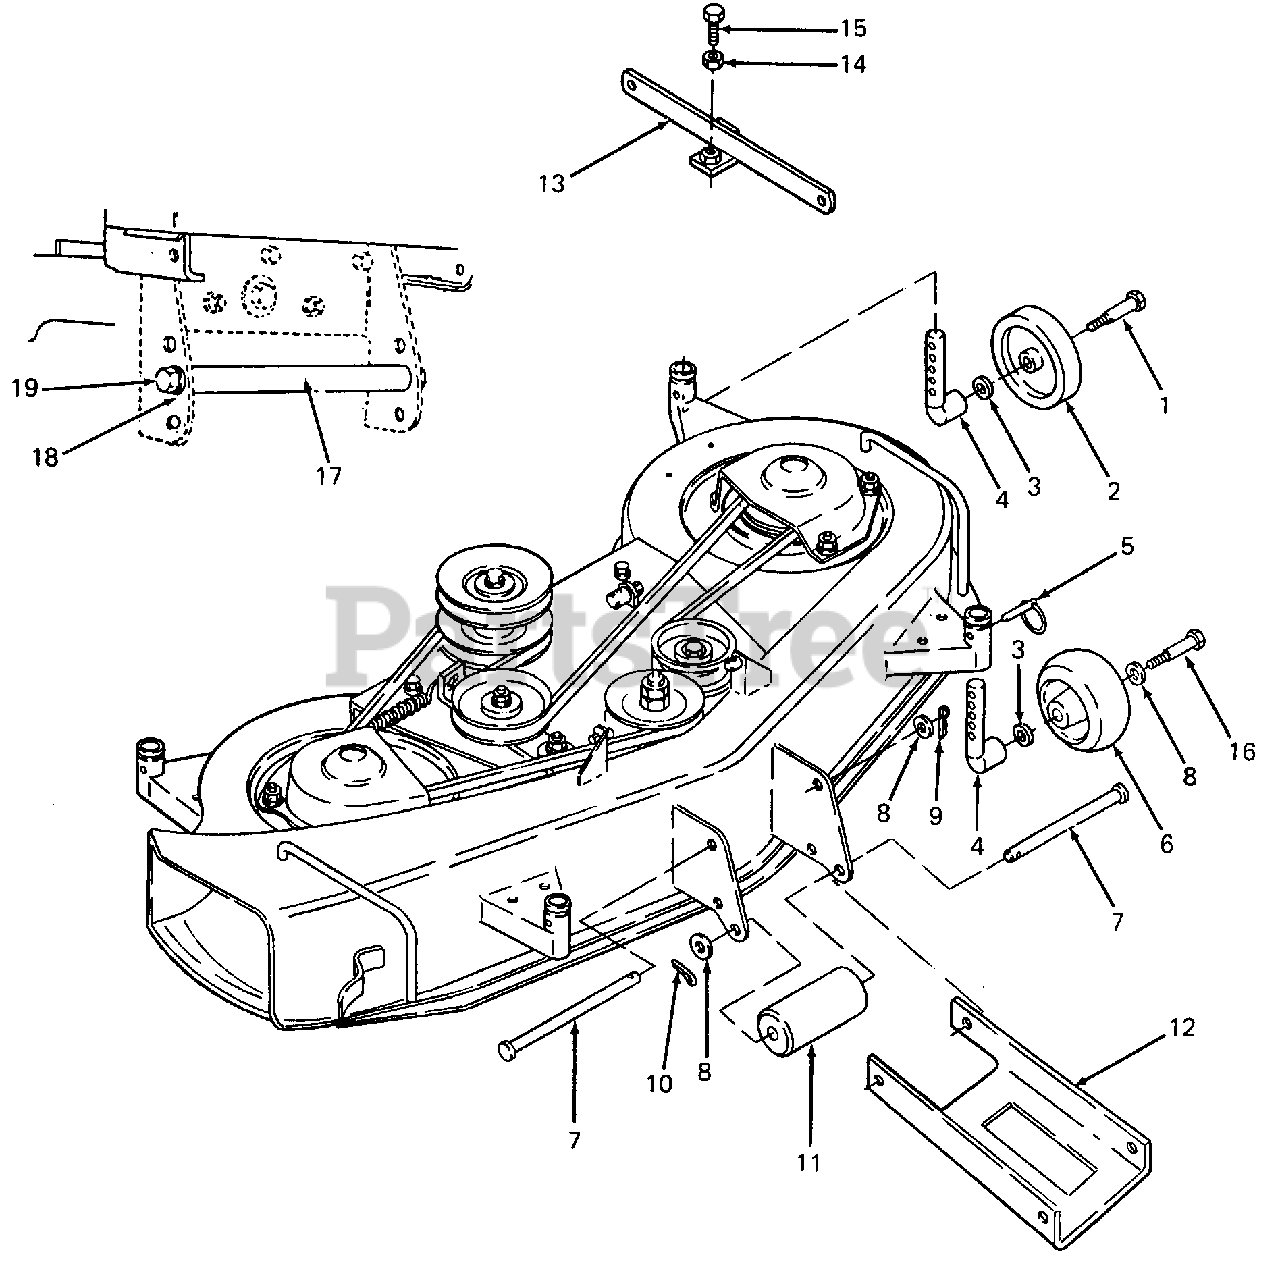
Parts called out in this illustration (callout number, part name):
1	Screw, Shoulder
2	Wheel, Gage, 5 in. Dia
3	Washer, Bell
4	Axle, Deck
5	Pin, Clevis w/Detent Ball
6	Wheel, Ball w/Fitting, 5 in. Dia
7	Pin, Clevis, 1/2 X 7.68 Lg
8	Washer, Flat, .510 X 1.0 X .06
9	Pin, Internal Cotter
10	Pin, Cotter, 3/16 X 1.0 Lg
11	Roller, Front
13	Stop, Lift
14	Nut, Hex Jam, 3/8-16 GR5
15	Screw, Hex Cap, 3/8-16 X 1.0 Lg GR5
16	Screw, Shoulder
17	Rod, Reinforcement
18	Washer, Lock, 1/2
19	Screw, Hex Cap, 1/2-13 X .75 Lg GR5
